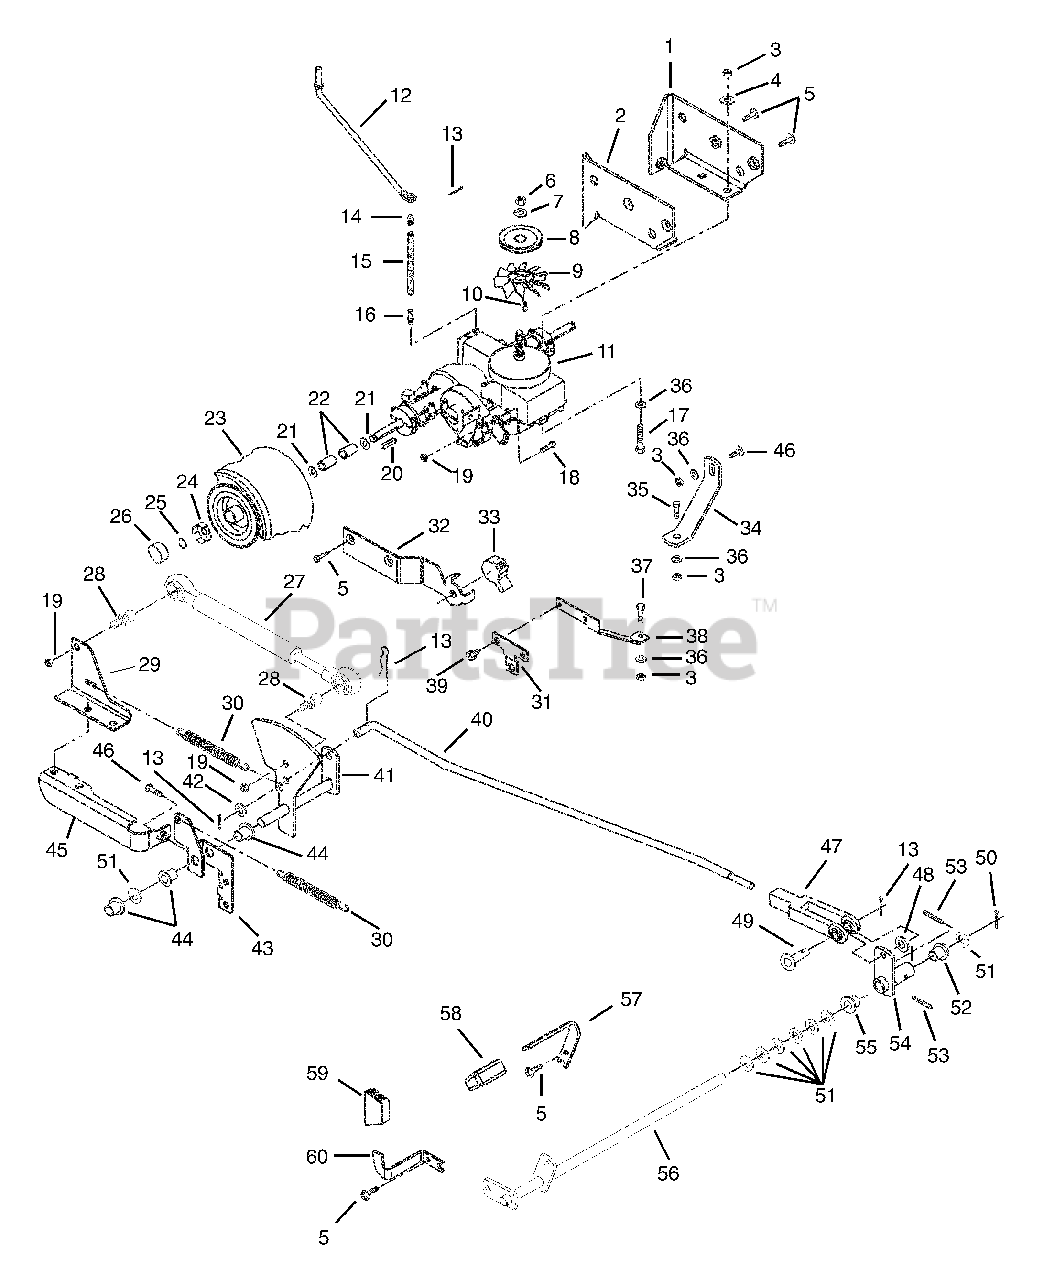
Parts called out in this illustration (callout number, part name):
1	MOUNT - TRANS. LH
2	MOUNT - TRANS. RH
3	@NUT-LK-CTR .31-18 YWZC
4	WSHR-FL-STL .328X.875X.062YWZC
5	@SCR-TAP .38-16X1.00 HWH TR YZ
6	NUT-JAM .50-20 GR2 YWZC
7	@WSHR-LK .50X.125 REG YWZC
8	SHEAVE - TRANSAXLE
10	SCR-TAP 10-24X.484 HWH TR
11	TRANSAXLE- HYDRO #325-0750
12	ROD - TRANS. DISCONNECT
13	@PIN-CTR .09X.75 EXTPRSQCT YWZ
14	CAP-VENT .50
15	HOSE- VENT .50ID X 7.50LONG
16	FTG-STR .50 O-RING
17	@BLT-HEX .31-18X2.50 GR5 YWZC
18	@BLT-HEX .31-18X.75 GR5 YWZC
19	@NUT-LK-CTR .31-18 YWZC
20	KEY-SQ .188X2.0X.188 SAE 8630
21	WSHR-FL-STL.755X1.375X.062YWZC
22	BSHG-SLV .750X1.125X1.062
23	T/WHL ASSY 20X8.00-8
24	SPINDLE CUP
25	RG-RTNG-EXT .750X.050
26	HUB CAP
27	DAMPER - HYDRAULIC
28	STUD- BALL
29	ANCHOR - SPRING - TOP
30	SG-TENS .085X.60X5.13 WLD8.3
31	SUPPORT - SHIFT ARM
32	MOUNT - MAGNET
34	STRAP - TORQUE L.H.
35	@BLT-HEX .31-18X1.50 GR5 YWZC
36	@WSHR-FL-STL.344X.688X.065YWZC
37	@BLT-HEX .31-18X2.25 GR5 YWZC
38	STRAP - TORQUE RH
39	SCR-TAP .312-18X.50 HWH TR BL
40	ROD - SHIFT
41	ARM - SHIFT
42	@WSHR-FL-STL.406X.812X.065 YWZ
43	PIVOT - REVERSE
44	BSHG-FLG .508X.645X.459X.75 NY
45	ANCHOR - SPRING - BOTTOM
46	@BLT-HEX .31-18X.75 GR5 YWZC
47	YOKE, .312-24 X 2.25
48	WSHR-FL-STL .390X.75X.125 YWZC
49	PIN-CLEV .312X.822 HDND PL
50	@PIN-CTR .12X1.00 EXTPRSQCT YZ
51	WSHR-FL-STL .52X.827X.062 YWZC
52	BSHG-FLG .515X.750X.745X1.00NY
53	PIN-GRV .188X1.25 TP A
54	ARM & HUB
55	BSHG-FLG .502X1X.750
56	SHAFT - PEDAL
57	PEDAL - FORWARD
58	COVER - PEDAL - FORWARD
59	COVER - PEDAL - REVERSE
60	PEDAL - REVERSE
